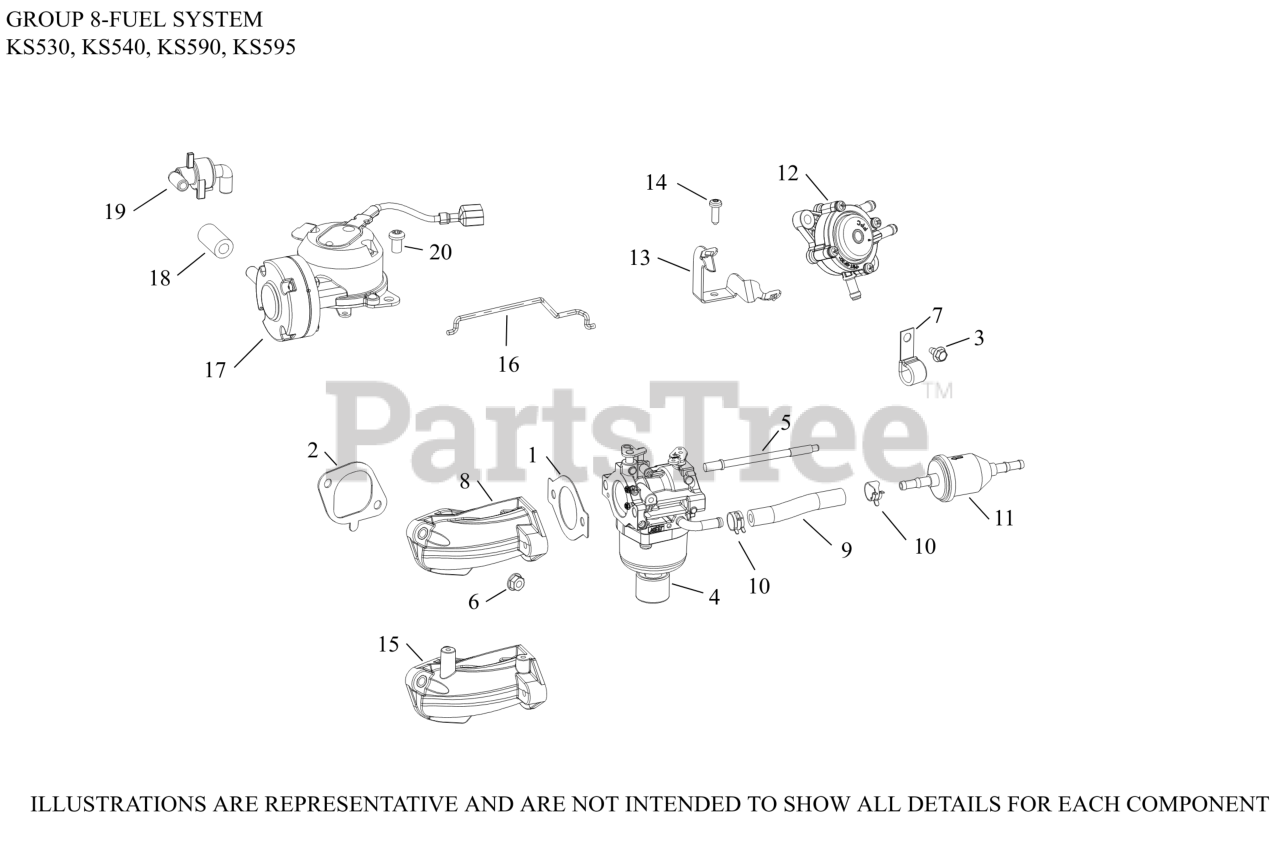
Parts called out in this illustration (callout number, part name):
1	GASKET, CARBURETOR (THROTTLE)
2	GASKET, INTAKE MANIFOLD
3	SCREW, THREAD FORMING
4	KIT,CARB(NIKKI)
5	STUD, CARBURETOR
6	NUT, FLG M6X1.0
7	CLIP, CABLE
8	MANIFOLD, INTAKE ASSEMBLY
9	HOSE,LW PERM.FUEL 24.00"-USE 25 111 81-S
10	SPRING CLAMP, HOSE
12	PUMP, FUEL (PULSE)-(#2539326S)
13	BRACKET, FUEL PUMP
NI	HIGH ALTITUDE KIT (5000 FT)
NI	KIT, OVERHAUL
NI	KIT, CHOKE SHAFT
NI	KIT, O-RING
NI	KIT, SOLENOID (NIKKI)
NI	KIT, BOWL WITH O-RINGS
NI	KIT, FLOAT & INLET NEEDLE FOR FUEL PUMP
NI	KIT, THROTTLE SHAFT
NI	MASKING CAP
